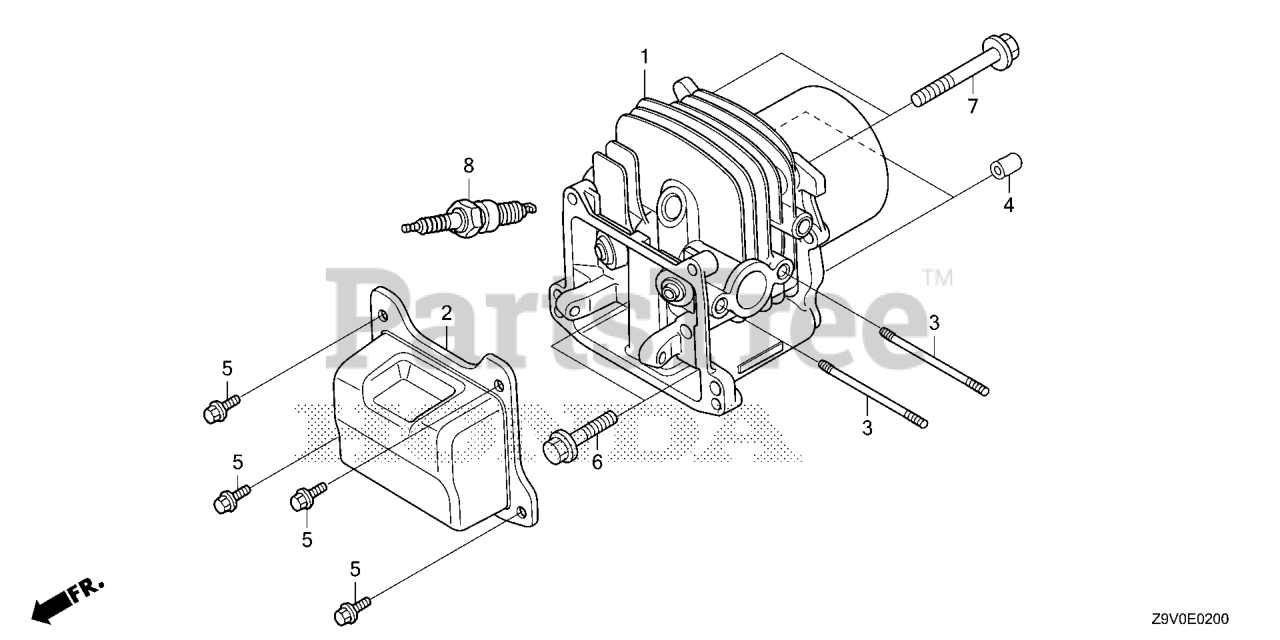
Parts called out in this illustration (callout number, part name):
1	CYLINDER
2	COVER, HEAD
3	BOLT, STUD (6X82) (CT200)
4	PIN A, DOWEL (8X14)
5	BOLT, FLANGE (6X14)
6	BOLT, FLANGE (8X25)
7	BOLT, FLANGE (8X40)
8	SPARK PLUG (BPR5ES) (NGK)
